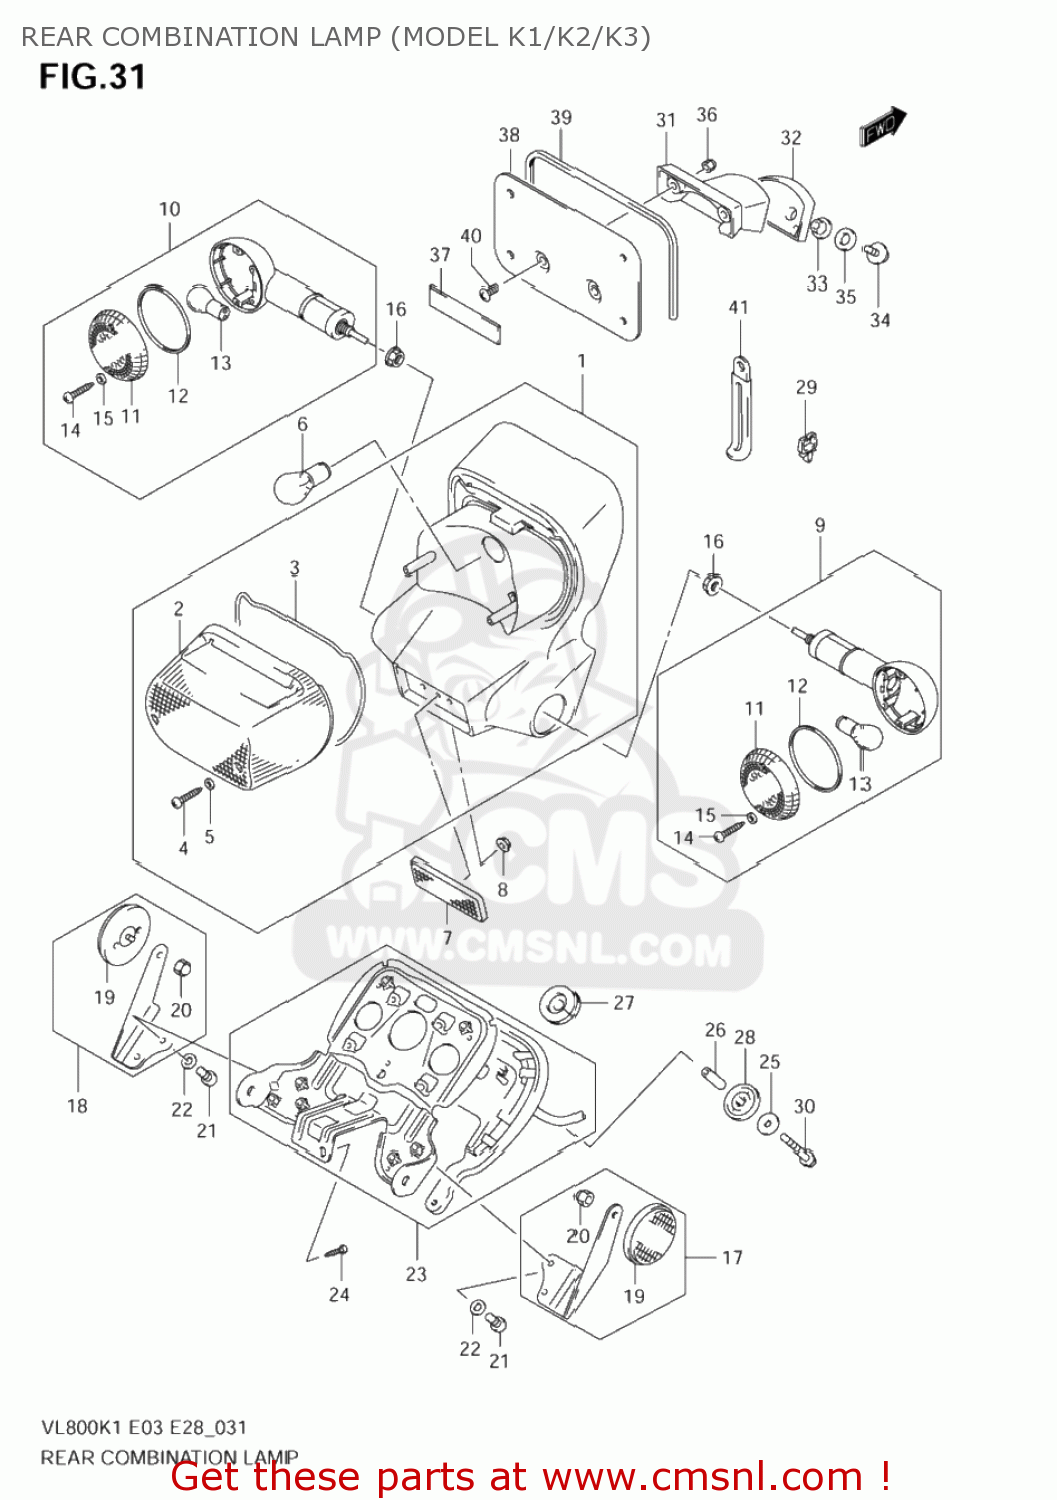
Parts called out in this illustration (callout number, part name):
1	LAMP UNIT
2	LENS
3	GASKET,FR TURN SIGNAL LAMP (NAS)
4	SCREW
5	GASKET (NAS)
6	BULB(12V21/5W)
7	REFLECTOR ASSEMBLY,REAR
8	NUT
9	LAMP ASSY,RR TURNSIGNAL,R
10	LAMP ASSY,RR TURNSIGNAL,L
11	LENS
12	GASKET (NAS)
13	BULB(12V21W)
14	SCREW
15	GASKET (NAS)
16	NUT
17	REFLEX REFLECTOR,R
18	REFLEX REFLECTOR,L
19	REFLEX REFLECTOR,RR
20	NUT
21	SCREW
22	LOCK,WASHER
23	SOCKET & CORD ASSY
24	SCREW
25	WASHER(6.5X20X1.6)
26	SPACER(6.5X9X23)
27	GROMMET
28	CUSHION
29	CLAMP
30	BOLT
31	STAY,LICENSE PLATE HOLDER
32	CUSHION,LICENSE HOLDER STAY
33	WASHER
34	BOLT
35	WASHER(6.5X18X1.6)
36	NUT
37	PROTECTOR(20X90)X1.0
38	HOLDER,LICENSE
39	MOLDING
40	SCREW
41	CLAMP(L:65)
